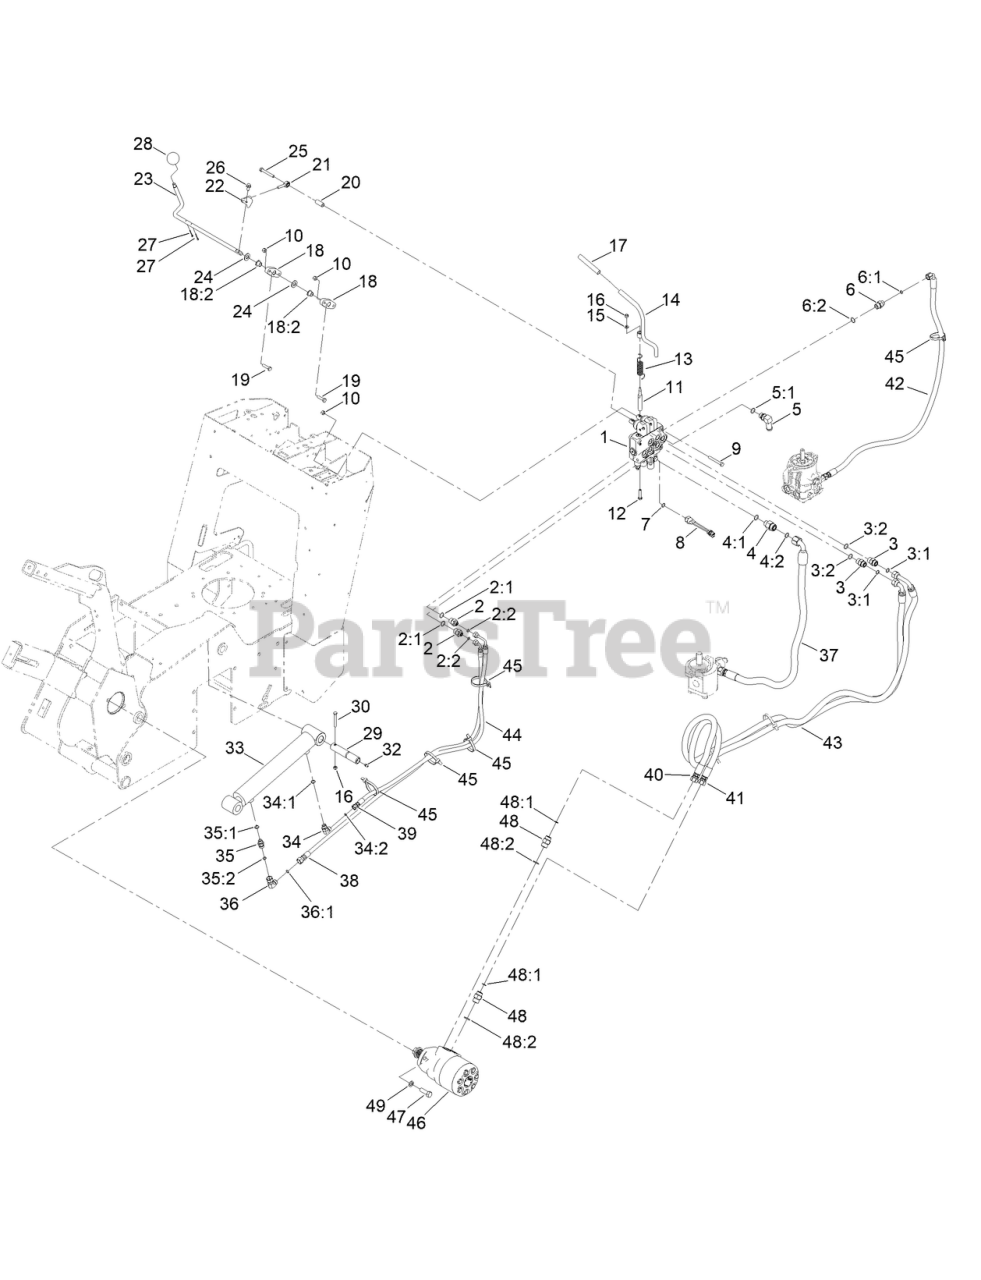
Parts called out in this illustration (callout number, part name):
1	HYD VALVE ASM
2	FITTING-STR
2:1	O-RING
2:2	O-RING
3	FITTING-STRAIGHT
3:1	O-RING
3:2	O-RING
4	FITTING-STRAIGHT
4:1	O-RING
4:2	O-RING
5	FITTING-ELBOW, 90
5:1	O-RING
6	FITTING-STRAIGHT
6:1	O-RING
6:2	O-RING
7	O-RING
8	SWITCH-BALL
9	SCREW-HH
10	NUT-LOCK, NI
11	SPACER-HIFLO
12	SCREW-HH
13	SPRING-TORSION
14	LEVER-AUXILIARY
15	WASHER-FLAT
16	NUT-LOCK, NI
17	GRIP-RUBBER
18	BUSHING ASM
18:2	BUSHING-FLANGE
19	SCREW-HH
20	SPACER
21	BEARING-ROD END
22	BRACKET-CONTROL
23	ROD-LEVER, CYLINDER
24	WASHER-FLAT
25	SCREW-HH
26	SCREW-HHF
27	PIN-COTTER
29	PIN-PIVOT
30	SCREW-HH
32	FITTING-GREASE
33	HYD CYLINDER ASM
34	FITTING-ELBOW, 90 DEG
34:1	O-RING
34:2	O-RING
35	VALVE-CHECK
35:1	O-RING
35:2	O-RING
36	FITTING-HYD, 90 DEG
36:1	O-RING
37	HOSE-HYD
38	HOSE-HYD
39	HOSE-HYD
40	HOSE-HYD
41	HOSE-HYD
42	HOSE-HYD
43	SLEEVE-PROTECTIVE
44	SLEEVE-PROTECTIVE
45	TIE-CABLE
46	HYD MOTOR ASM
47	SCREW-HH
48	FITTING-STRAIGHT
48:1	O-RING
48:2	O-RING
49	WASHER-LOCK
